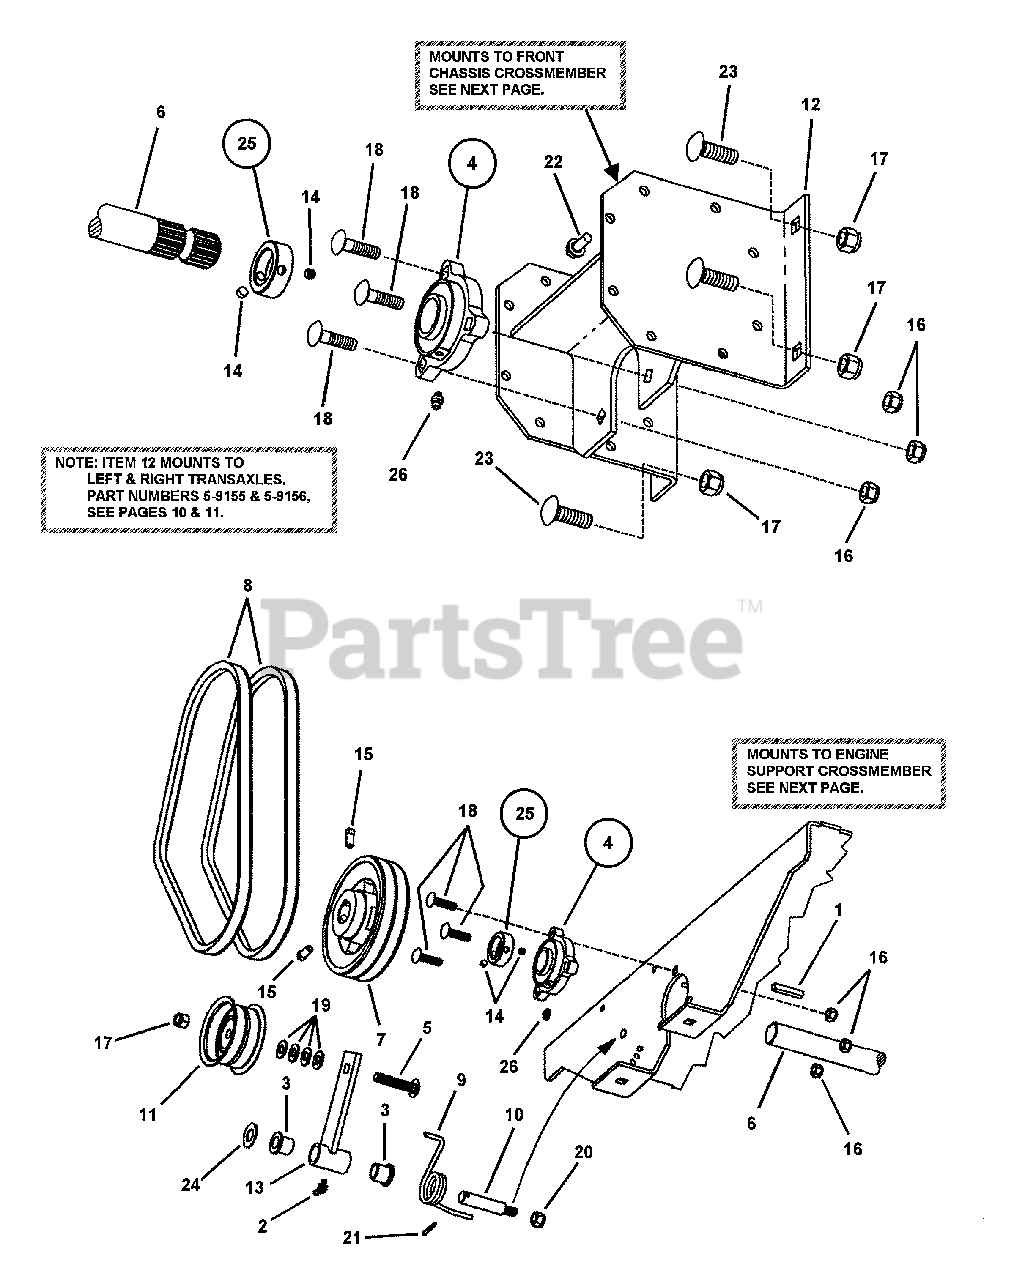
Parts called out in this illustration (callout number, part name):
1	KEY, 1/4" Square x 2"
2	FITTING, Lube
3	BUSHING
4	ASSEMBLY, Bearing
5	BOLT, 3/8-16 x 2" Carriage, Grade 2
6	DRIVE SHAFT, Deck (1" Diameter, 15 Spline)
7	PULLEY, Double V (5.45 O.D., A Section)
8	BELT, Deck Drive (AX 37.25" Eff. Length)
9	SPRING, Tension
10	PIN, 3/8-24 UNF
11	FLAT IDLER, 2.75 O.D. x 1-1/4" Wide
12	WELDMENT, Bearing Mount
13	IDLER ARM, Straight (Weldment)
14	SET SCREW, 1/4-20 x 1/4" Cone Point
15	SET SCREW, 5/16-18 x 5/8 Knurled Cup Point
16	NUT, 5/16-18 HEX NYLON LOCK
17	NUT, 3/8-16 HEX NYLON LOCK
18	BOLT, 5/16-18 x 1-1/4", Square Neck Carriage Grade 5
19	WASHER, 3/8" Flat
20	NUT, 3/8-24 Hex Nyloc
21	COTTER-PIN, 1/8 x 3/4"
22	SCREW, 1/4-20 x 5/8", Hex Flange Lock, Grade 5
23	BOLT, 3/8-16 x 1-1/4" Carriage, Grade 5
24	WASHER, 9/16 Flat
25	ASSEMBLY, Lock Collar, 1"
26	LUBE FITTING, Straight (press-fit for .187 dia. Hole)
